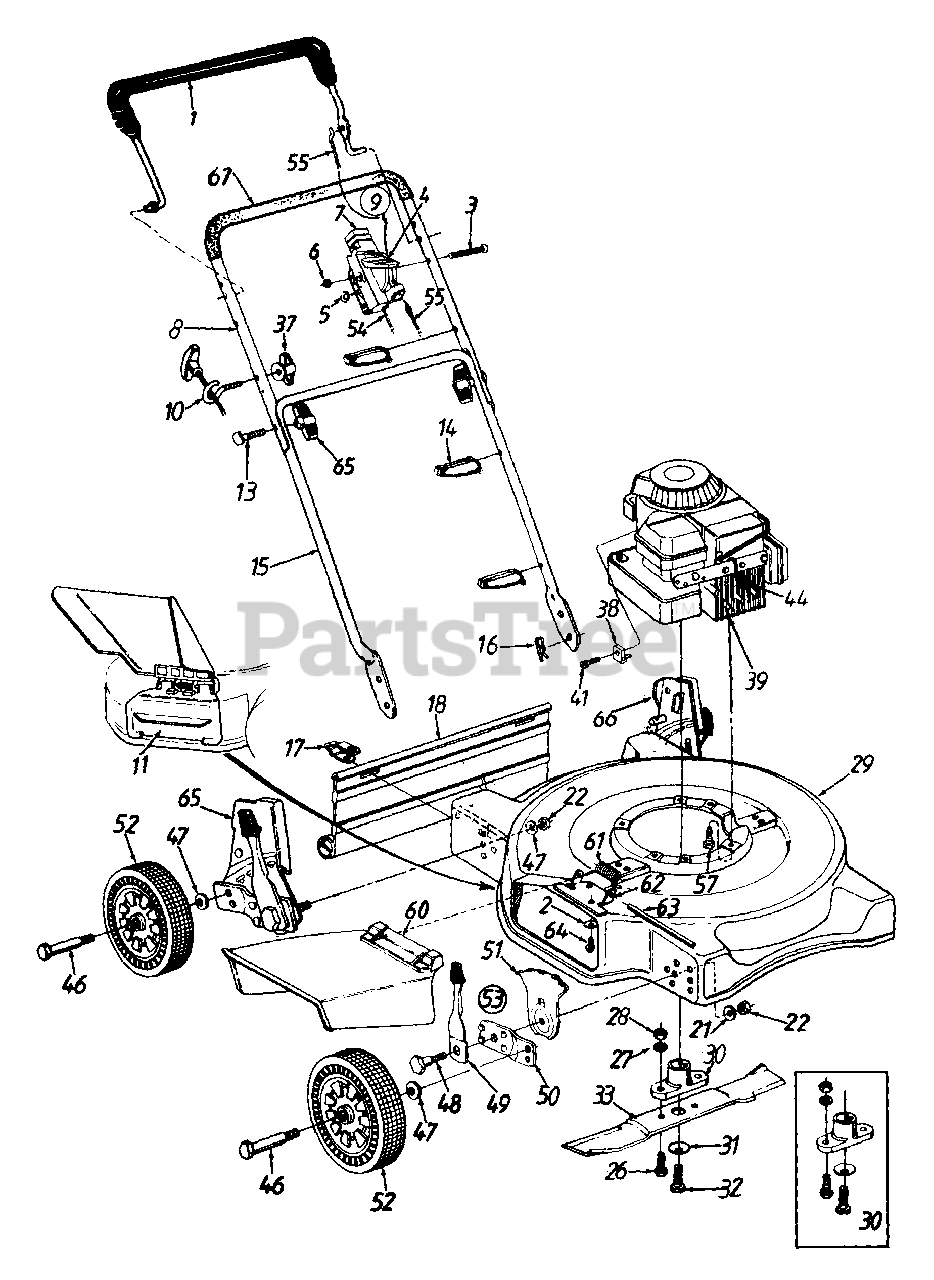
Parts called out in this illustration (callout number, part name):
1	Control Handle Ass'y. w/Plastic
2	Bell-Wash. 1/4" I.D.
3	Oval C-Sunk Mach. Scr.
4	Throttle Lever
5	Spr. Wash. .66" I.D.
6	Hex L-Nut 1/4-20 Thd.
7	Throttle Body
10	Rope Guide
13	Curved Hd. Bolt 5/16-18 x 2" Lg.
14	Cable Tie
16	Hairpin Cotter
17	Hinge Clip
18	Rear Flap
22	Hex Nut 3/8-16 Thd.
26	Hex Bolt 3/8-24 x 1" Lg.
27	L-Wash. 3/8" I.D.
28	Hex Nut 3/8-24 Thd.
31	Bell-Wash. .39" I.D.
32	Hex Bolt 3/8-24 x 1.5" Lg.
33	20" Blade
37	Wing Nut 1/4-20 Thd.
38	Cable Clamp
39	Engine
41	Hex Wash. Hd. Tap Scr. #10-32 x .62" Lg.
44	Spark Plug Boot
47	Bell-Wash. .400" I.D. x .88"
48	Shld. Bolt .50" Dia. x .357"
49	Spring Lever Ass'y. w/Knob
51	Height Adj. Plate
52	Wheel Ass'y. Comp.
53	Height Adj. Ass'y. Comp. - R.F.
54	Throttle Cable - 51"
55	Control Cable - 39"
57	Hex L-Wash. Hd. Scr. 3/8-16 x 1.0" Lg.
60	Chute Deflector Ass'y.
61	Torsion Spring
62	Adapter Plate
63	Hinge Pin
64	Hex Self-Tap Scr. 1/4-20 x .5"
67	Foam Grip
